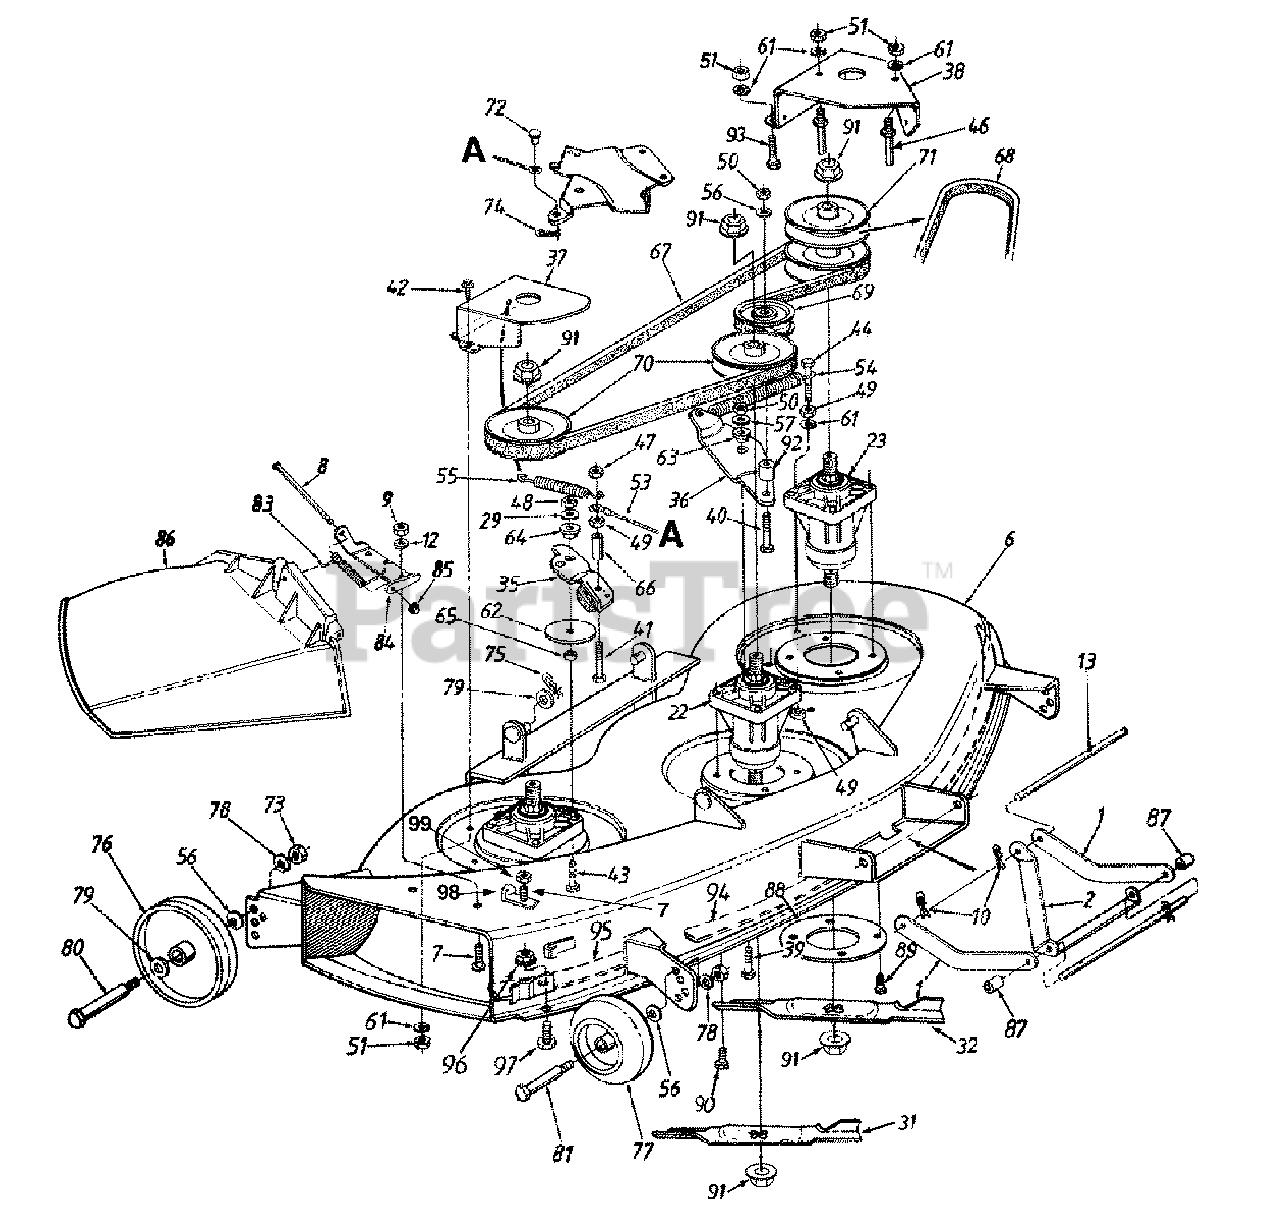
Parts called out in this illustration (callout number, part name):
8	Hinge Pin
9	Hex Nut 1/4-20 Thd. (Gr. 5)
10	Hairpin Clip
12	Bell-Wash. 1/4" I.D.
13	Deck Connecting Rod
22	Spindle Ass'y. (R.H. & Center)
23	Spindle Ass'y. (L.H.)
29	Lock Wash. 5/16" I.D.
31	Blade 14.88" Lg. (Middle)
32	Blade 16.28" Lg. (R.H. & L.H.)
35	Deck Brake Brkt. Ass'y.
36	Idler Bracket
39	Hex Bolt 3/8-24 x 1.0" Lg.
40	Hex Bolt 3/8-24 x 2" Lg.
41	Hex Bolt 1/4-28 x 1.75" Lg.
42	Hex Wash. Hd. Tap-Scr. 1/4-20 x .5"
43	Hex Bolt 5/16-24 x 1.5"
44	Hex Bolt 1/4-28 x 1.5" Lg.
46	Belt Guard Pin 1/4" Dia.
47	Hex Cent. L-Nut 1/4-28 Thd.
48	Hex Nut 5/16-24 Thd.
49	Hex Nut 1/4-28 Thd.
50	Hex Nut 3/8-24 Thd.
51	Hex Nut 1/4-20 Thd. (Gr. 5)
53	Brake Cable Ass'y.
54	Extension Spring 6.17" Lg.
55	Extension Spring 3.97" Lg.
56	Bell-Wash. .38" I.D. x .88" O.D.
57	Bell-Wash. .39" I.D. x 1.13" O.D.
61	L-Wash. 1/4" I.D.
62	Fl-Wash. 5/16" I.D. x 3" O.D.
63	Shld. Spacer .625" I.D.
64	Shld. Spacer
65	Spacer .34" I.D.
66	Spacer .326" I.D.
67	V-Belt
68	V-Belt
69	Fl-Idler Pulley 3.5" O.D.
70	Pulley 5.0" Dia.
71	Double Pulley 5.0" Dia.
72	Clevis Pin 1/4" Dia. x .53" Lg.
73	Hex Nut 3/8-16 Thd.
74	Intern. Cotter Pin 5/16" Dia.
75	Intern. Cotter Pin 3/8 Dia.
76	Deck Wheel 5" Dia.
77	Deck Wheel w/Insert 5" Dia.
78	L-Wash. 3/8" I.D.
79	Fl-Wash. .531" I.D.
80	Shoulder Bolt .498" Dia. x 1.64" Lg.
81	Shoulder Bolt
83	Torsion Spring
84	Hinge Mtg. Brkt.
85	Push Nut
86	Chute Ass'y. Comp.
87	Spacer 5/8" I.D. x 7/8" O.D.
90	Hex Wash. Hd. Scr. 5/16-18 x .75"
91	Hex Flange Nut 5/8-18 Thd.
92	Spacer .38" I.D.
93	Hex Bolt 1/4-20 x .5" Lg.
96	Hex Sems Nut 1/4-20 Thd.
97	Carriage Bolt 1/4-20 x .5" Lg.
98	Retainer Hook Bracket
99	Hex Lock Nut 1/4-20
